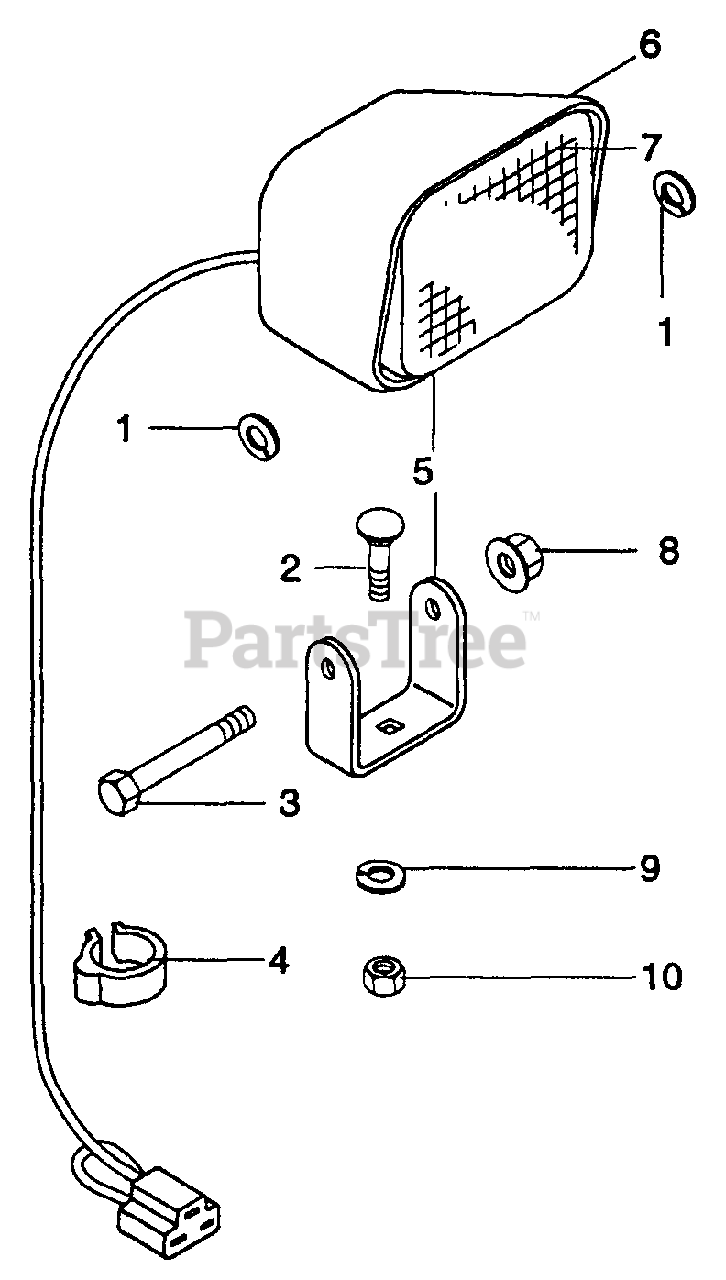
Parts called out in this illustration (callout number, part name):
1	WSHR-LK-EXT .313X.030 PL
2	BLT-RDHDSQNK .31-18X1.00 PL
3	BLT-HEX .31-18X2.50 PL GR2
4	CLAMP
5	HEADLIGHT
6	LENSE-FLOOD
7	BULB
8	NUT-FLG. .312-18 PL
9	WSHR-LK .312X.097 PL HVY
10	NUT-HEX .312-18
